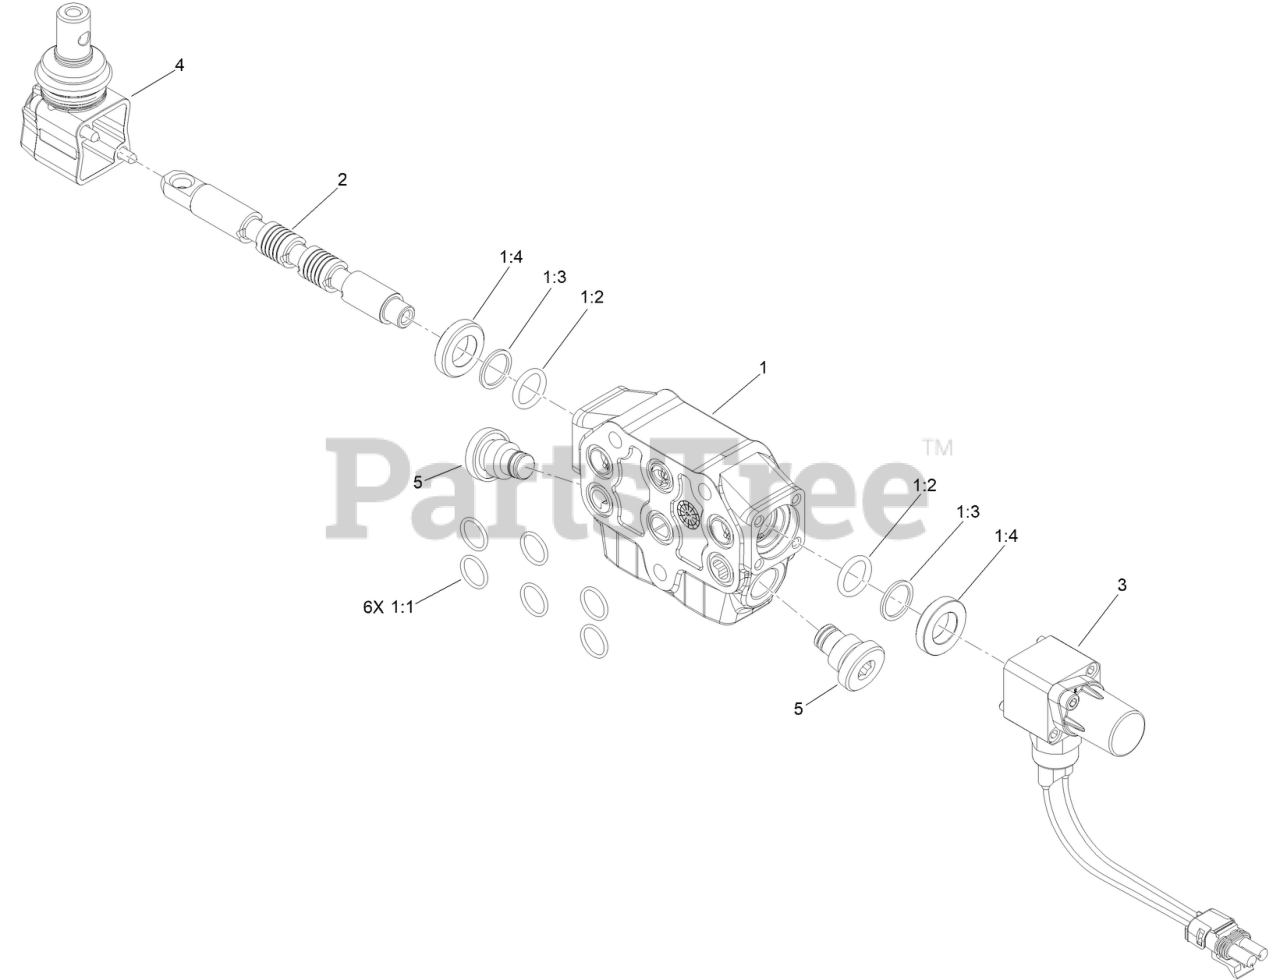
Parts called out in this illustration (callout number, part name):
1	SECTION-WORKING
1:1	O-RING
1:2	SEAL-VALVE
1:3	SEAL-VALVE
1:4	SEAL-VALVE
2	VALVE-SPOOL
3	KIT-CONTROL
4	LEVER-VALVE
